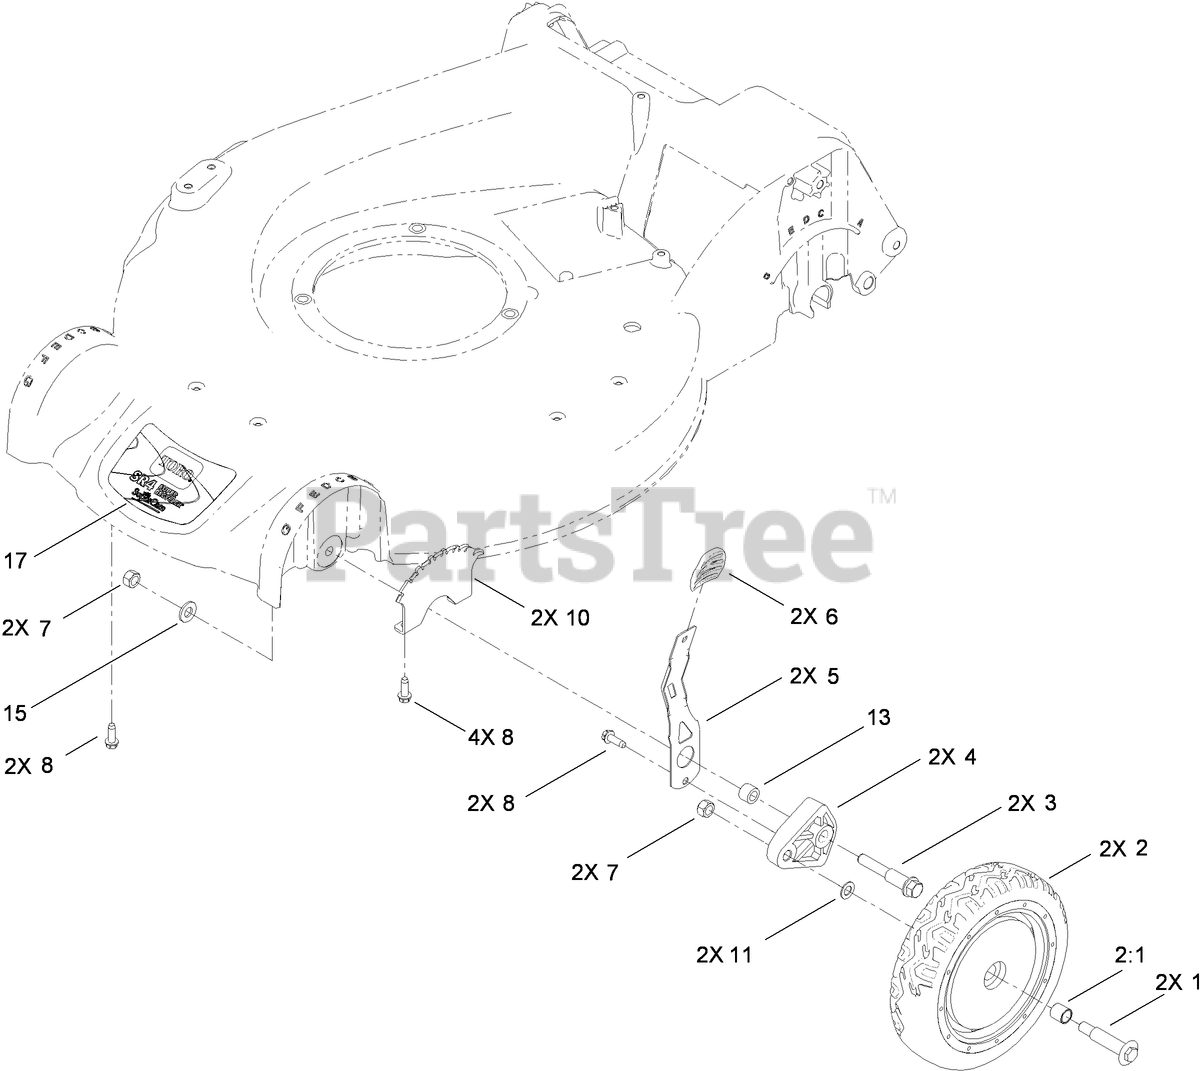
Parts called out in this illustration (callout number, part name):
1	BOLT-SHOULDER
2	WHEEL ASM
2:1	BUSHING
3	SCREW-SHOULDER
4	ARM-PIVOT
5	ARM-SPRING
6	KNOB-LEVER, HOC
7	LOCKNUT
8	SCREW-HWHTF
10	PLATE-HOC
11	WASHER
13	SPACER-WHEEL
15	WASHER-FLAT
17	DECAL-SUPERCARE
